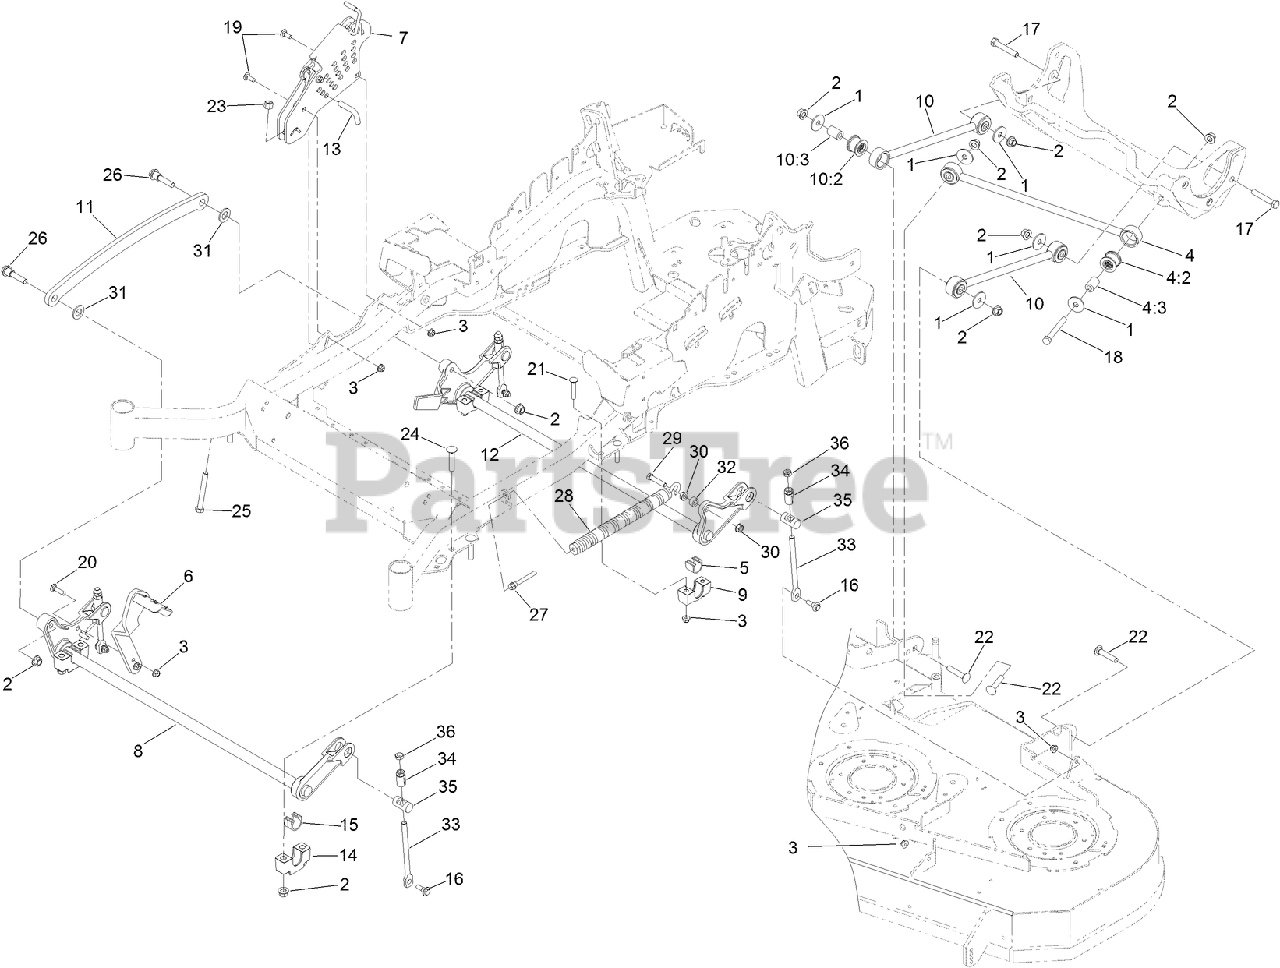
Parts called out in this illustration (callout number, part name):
1	WASHER-THRUST
2	NUT-LOCK
3	NUT-HF, NI
4	PANHARD ROD ASM
4:2	BUSHING-SUSPENSION, RUBBER
4:3	SPACER
5	BEARING-CROSS SHAFT, REAR
6	LEVER-FOOT
7	HOC ASM
8	DECKLIFT-FRONT
9	SUPPORT-CROSS SHAFT, BEARING REAR
10	DECK STRUT ASM
10:2	BUSHING-SUSPENSION, RUBBER
10:3	SPACER
11	LINK-LIFT, DECK
12	LIFT-DECK, REAR
13	PIN-HOC
14	SUPPORT-CROSS SHAFT, BEARING
15	BEARING-CROSS SHAFT, FRONT
16	SCREW-SHOULDER, HHF
17	SCREW-HH
18	SCREW-HH
19	BOLT-CARR
20	SCREW-CARR
21	SCREW-CARR
22	SCREW-CARR
23	NUT-LOCK, NI
24	BOLT-CARR
25	BOLT-TAP
26	SCREW-HHF, SHOULDER
27	BOLT-SHOULDER
28	SPRING-EXTENSION
29	SCREW-HH
30	NUT-HF
31	WASHER-FLAT
32	SPACER
33	LINK-ADJUSTER, DECK LIFT
34	ADJUSTER-LIFT, DECK
35	TRUNNION
36	NUT-JAM
